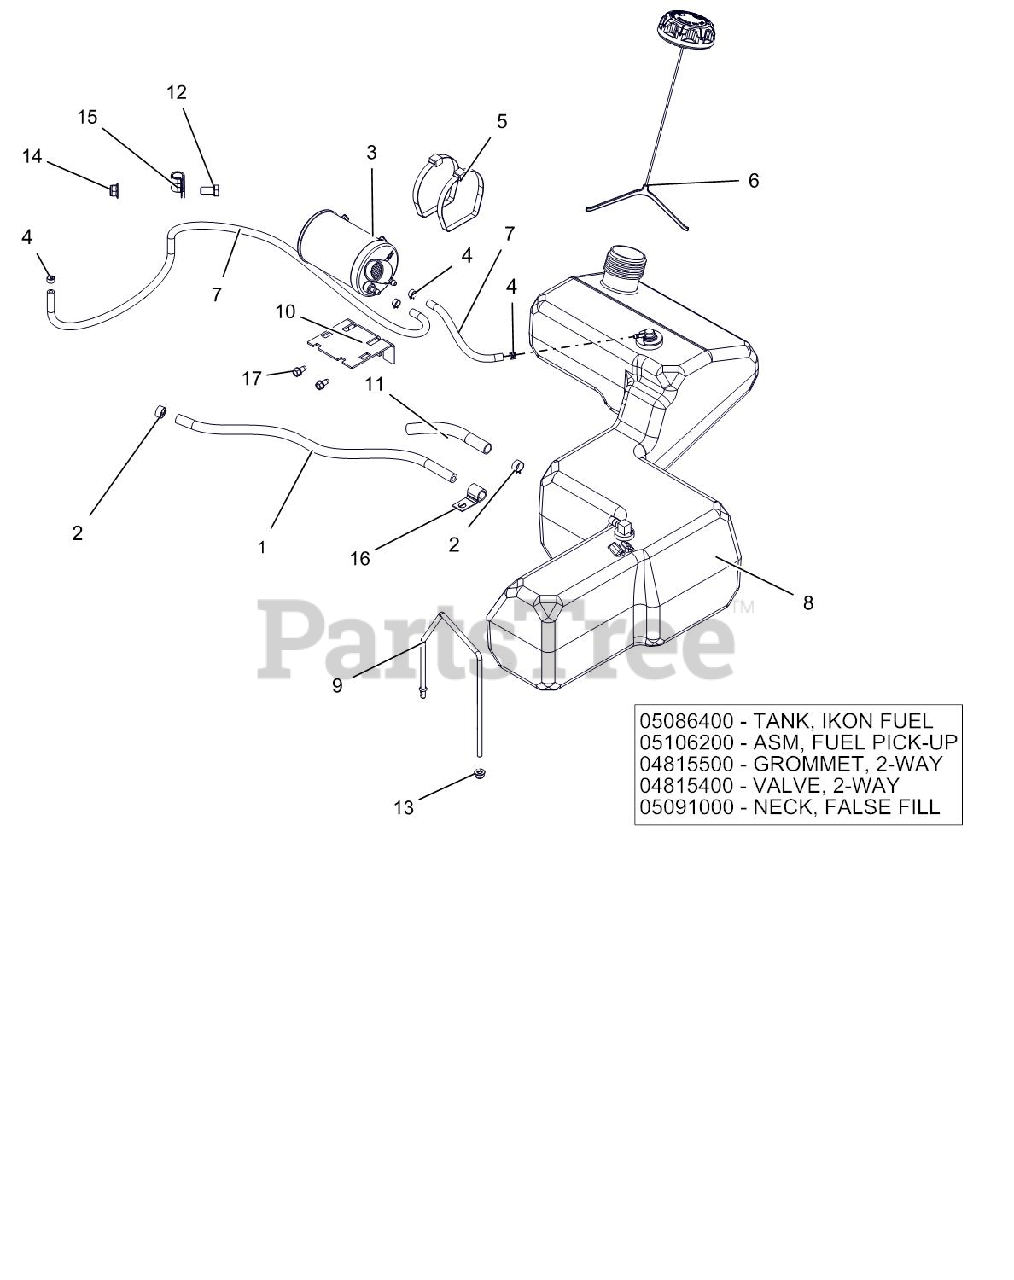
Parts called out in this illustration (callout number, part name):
1	HOSE, .25 LOW-PERM BULK GAS
2	CLAMP, FUEL LINE
3	CARBON CANISTER, 300CC
4	CLAMP-HOSE, SPRING .188
5	P-PLASTIC TIE STRAP LARGE
6	CAP, FUEL VENT-IN 2.25" RATCH.
7	HOSE, .188 30R7 BULK
8	VALVE, 2-WAY
8	GROMMET, 2-WAY
8	ASSEMBLY, FUEL TANK IKON(2017)
8	TANK, IKON FUEL (2017)
8	ASM, IKON FUEL PICK-UP
8	NECK, FALSE FILL-2017 IKON
9	BRKT, FUEL TANK HOLD DOWN
10	BRKT, MOUNT -CARB CANISTER
11	WRAP, ANTIABRASION .5X.064WALL
12	@BLT-HEX .38-16X.75 GR5 YWZC
13	@NUT-LK-NYL-FLG .25-20 YWZC
14	@NUT-LK-NYL-FLG .38-16 YWZC
15	CLAMP, CUSHIONED STEEL
16	J-CLAMP
17	SCR-TAP .25-20X.50 HWH TR YWZ
